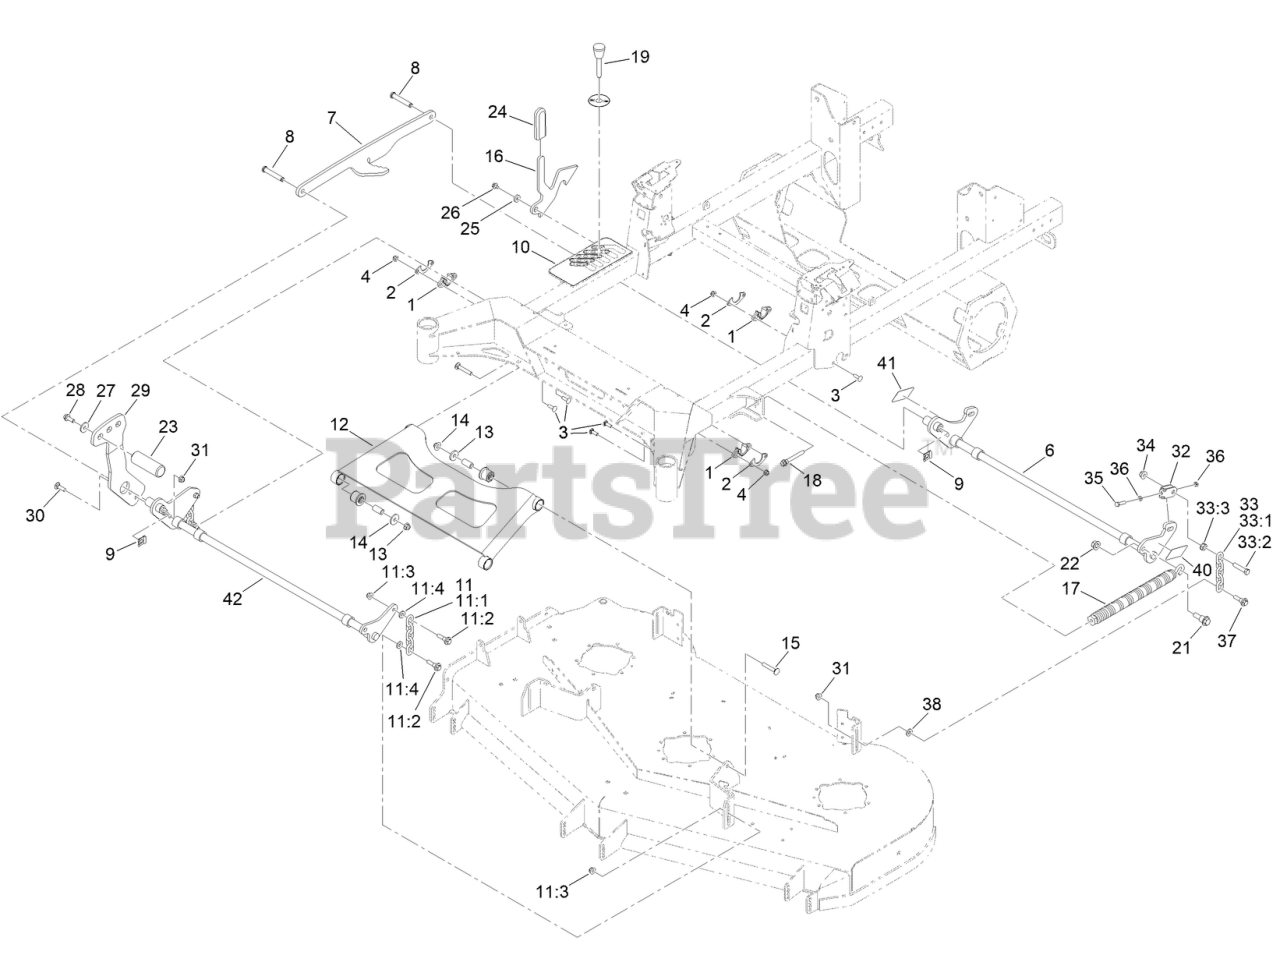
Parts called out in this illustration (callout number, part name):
1	BEARING-FLANGE
2	GUSSET-LIFT, DECK
3	SCREW-CARR
4	NUT-HF, NI
6	ADJ DECK LIFT SHAFT ASM
7	LINK-LIFT
8	PIN-CLEVIS
9	CLIP-PIN
10	DECAL-HOC
11	DECK CHAIN ASM
11:1	CHAIN-LIFT, DECK
11:2	BOLT-SHOULDER
11:3	NUT-HF, NI
11:4	SPACER
12	ASM-DECK STRUT W/ BUSHINGS
13	WASHER
14	NUT-FLANGE, NI
15	SCREW-CARR
16	PLATE-TRANSPORT LOCK
17	SPRING-EXTENSION
18	BOLT-SHOULDER
19	PIN-HOC
21	SCREW-SHOULDER, HHF
22	NUT-LOCK
23	PEDAL-FOOT LIFT
24	GRIP-LEVER
25	SPACER
26	SCREW
27	WASHER
28	SCREW-HHF
29	ARM-DECK LIFT [BLACK]
30	BOLT-CARR
31	NUT-HF, NI
32	YOKE-ADJUST, DECK
33	DECK LIFT CHAIN ASM
33:1	CHAIN-LIFT, DECK
33:2	SCREW-HH
33:3	NUT-HF
34	NUT-HF, NI
35	SCREW-HH
36	NUT-JAM
37	BOLT-SHOULDER
38	SPACER
40	DECAL-RAKE, LH
41	DECAL-RAKE, RH
42	DECK LIFT SHAFT ASM [BLACK]
